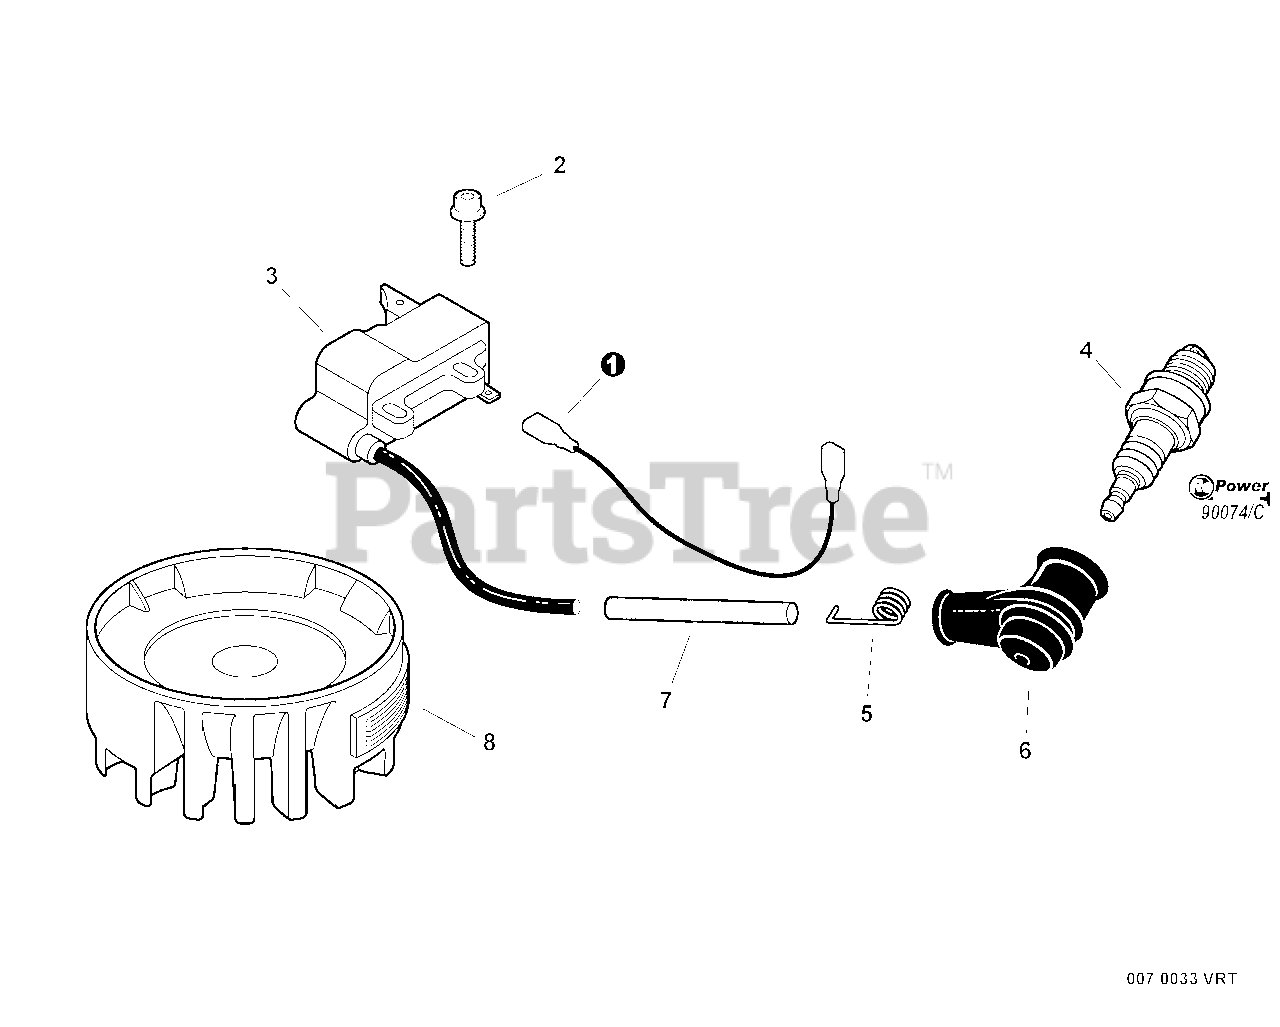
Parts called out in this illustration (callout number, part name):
1	LEAD - IGNITION
2	SCREW - 4X20
3	COIL, IGNITION
4	SPARK PLUG -- BPM-8Y
4	SPARK PLUG -- BPMR-8Y
5	TERMINAL, SPARK PLUG CAP
6	CAP, SPARK PLUG
7	TUBE, INSULATOR
8	FLYWHEEL
9	RePower TUNE-UP KIT
